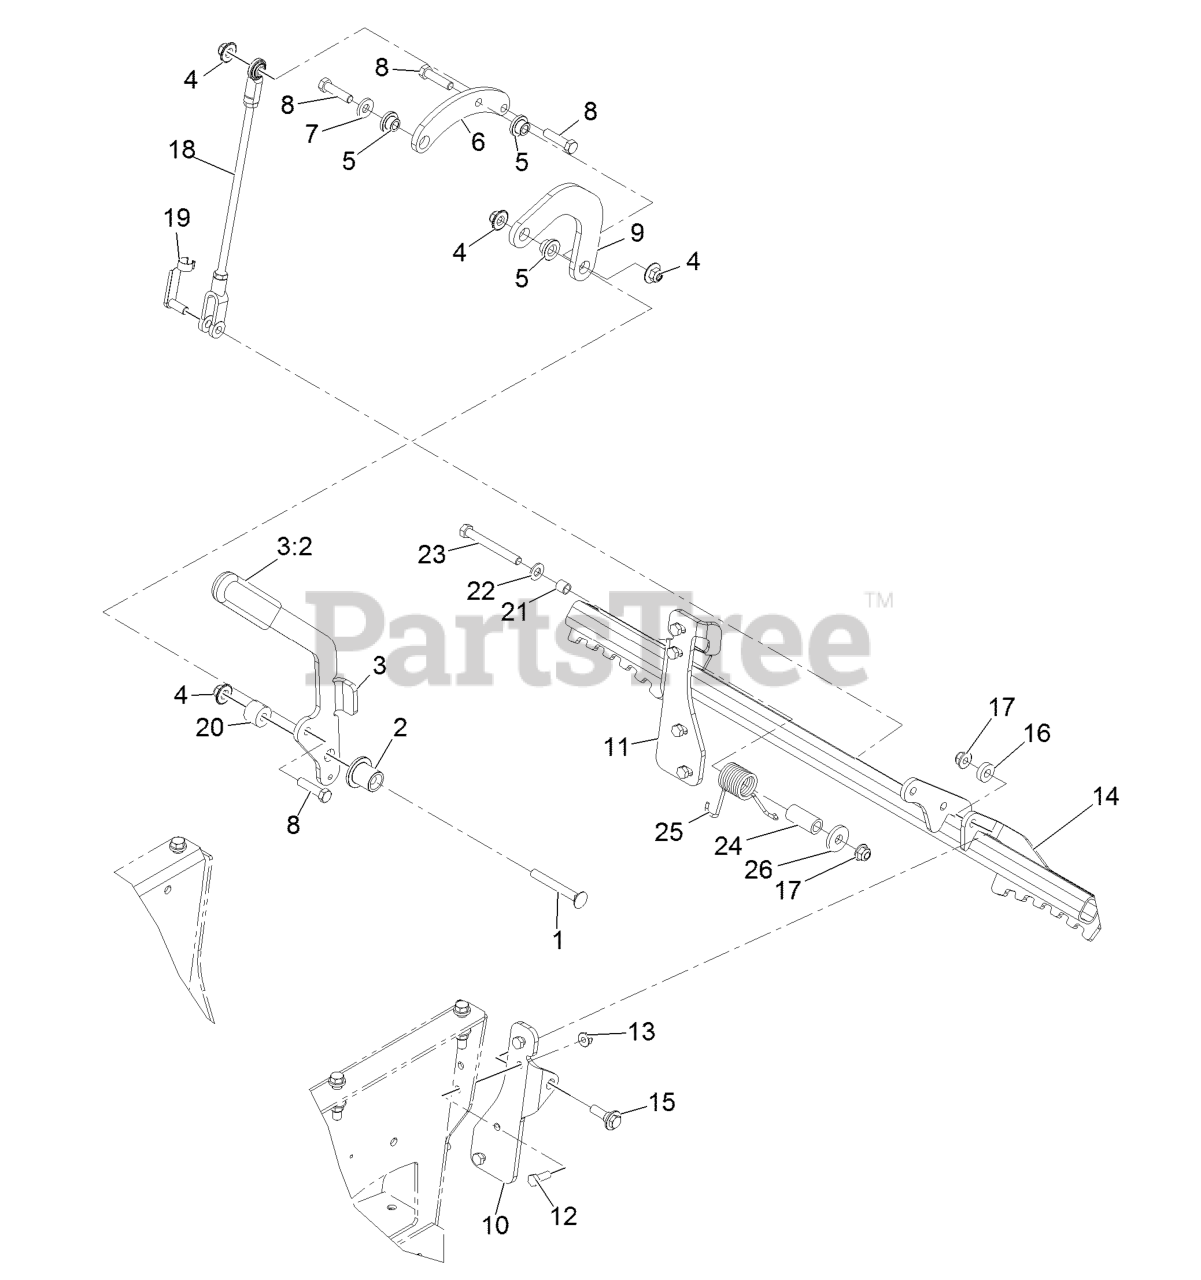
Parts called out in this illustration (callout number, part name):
1	SCREW-CARR
2	BUSHING-HANDLE
3	HANDLE-W/GRIP ASM
3:2	GRIP-LEVER
4	Nut-Nyloc 3/8-16 Flg
5	BUSHING-FLANGED
6	ARM-BRAKE BELLCRANK
7	WASHER-BELLEVILLE
8	SCREW-HH
9	LINK-BRAKE HANDLE
10	BRACKET-BRAKE MOUNT, LH
11	BRACKET-BRAKE MOUNT, RH
12	SCREW-HH
13	NUT-HF, NI
14	BAR-BRAKE
15	SCREW-SHOULDER, HWH
16	SPACER
17	NUT-HF, NI
18	ASM-BRAKE LINKAGE
19	PIN-SPRING, CLEVIS
22	WASHER-FLAT
23	SCREW-HH
25	SPRING-TORSION
